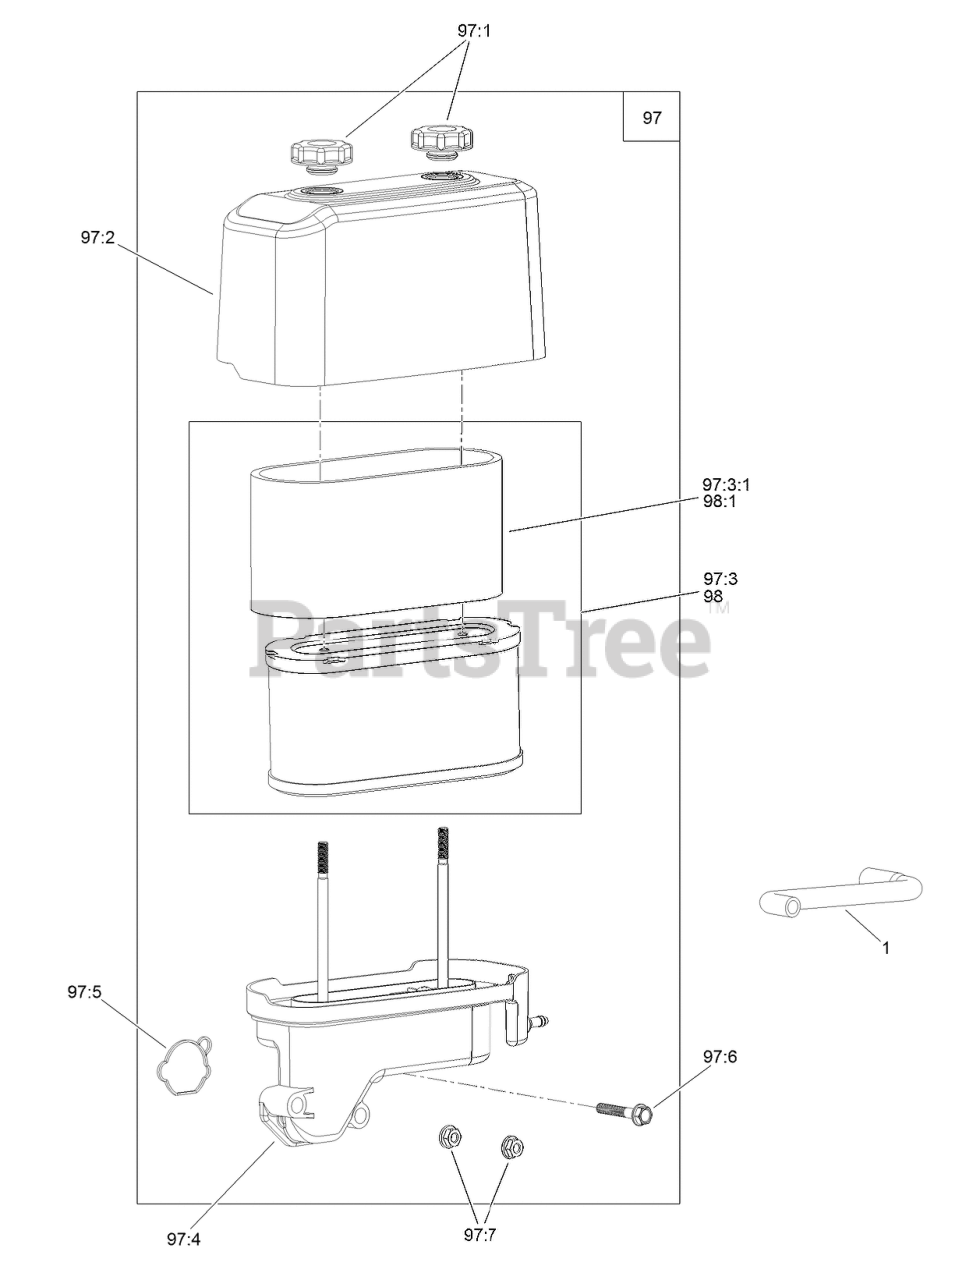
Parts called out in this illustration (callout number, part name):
1	TUBE-BREATHER
97	AIR FILTER ASM
97:1	NUT-SPEED
97:2	COVER-FILTER, AIR
97:3	AIR FILTER KIT
97:3:1	PREFILTER
97:4	BASE-FILTER, AIR
97:5	GASKET-CARBURETOR
97:6	SCREW-HHF
97:7	NUT-FLANGE
98	AIR FILTER KIT
98:1	PREFILTER
